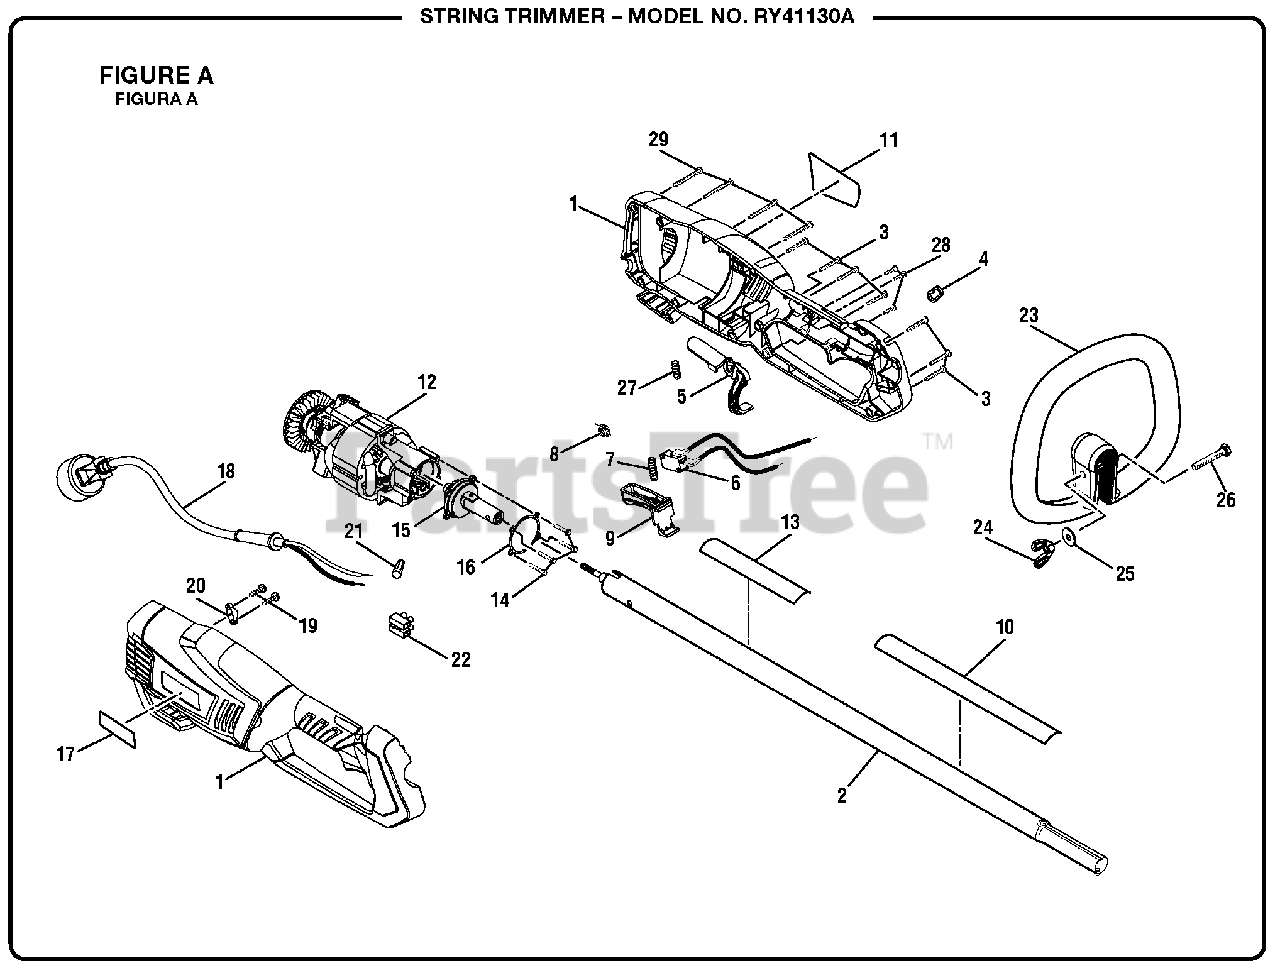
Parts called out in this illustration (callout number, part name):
1	Housing Assembly
2	Boom Assembly (Incl. Key Nos. 10 and 13)
3	Screw (M4 x 14 mm)
4	Strap Hook
5	Lock-Out Lever
6	Switch Assembly w/Leads
7	Compression Spring
8	Torsion Spring
9	Switch Trigger
10	Warning Label (French and Spanish)
11	Data Label/Warning Label (English)
12	Motor Assembly
13	Icon Strip Label
14	Screw (M4 x 10 mm)
15	Gear Assembly
16	Rubber Gasket
18	Power Cord Assembly
19	Screw (M3.5 x 12 mm)
20	Cord Clamp
22	Terminal Block
23	Front Handle Assembly (Inc. Key Nos. 24-26)
24	Wing Nut (1/4-20)
25	Washer (1/4 in.)
26	Bolt (1/4-20 x 40 mm)
27	Compression Spring
28	Screw (M2.9 x 10 mm)
29	Screw (M4 x 18 mm)
